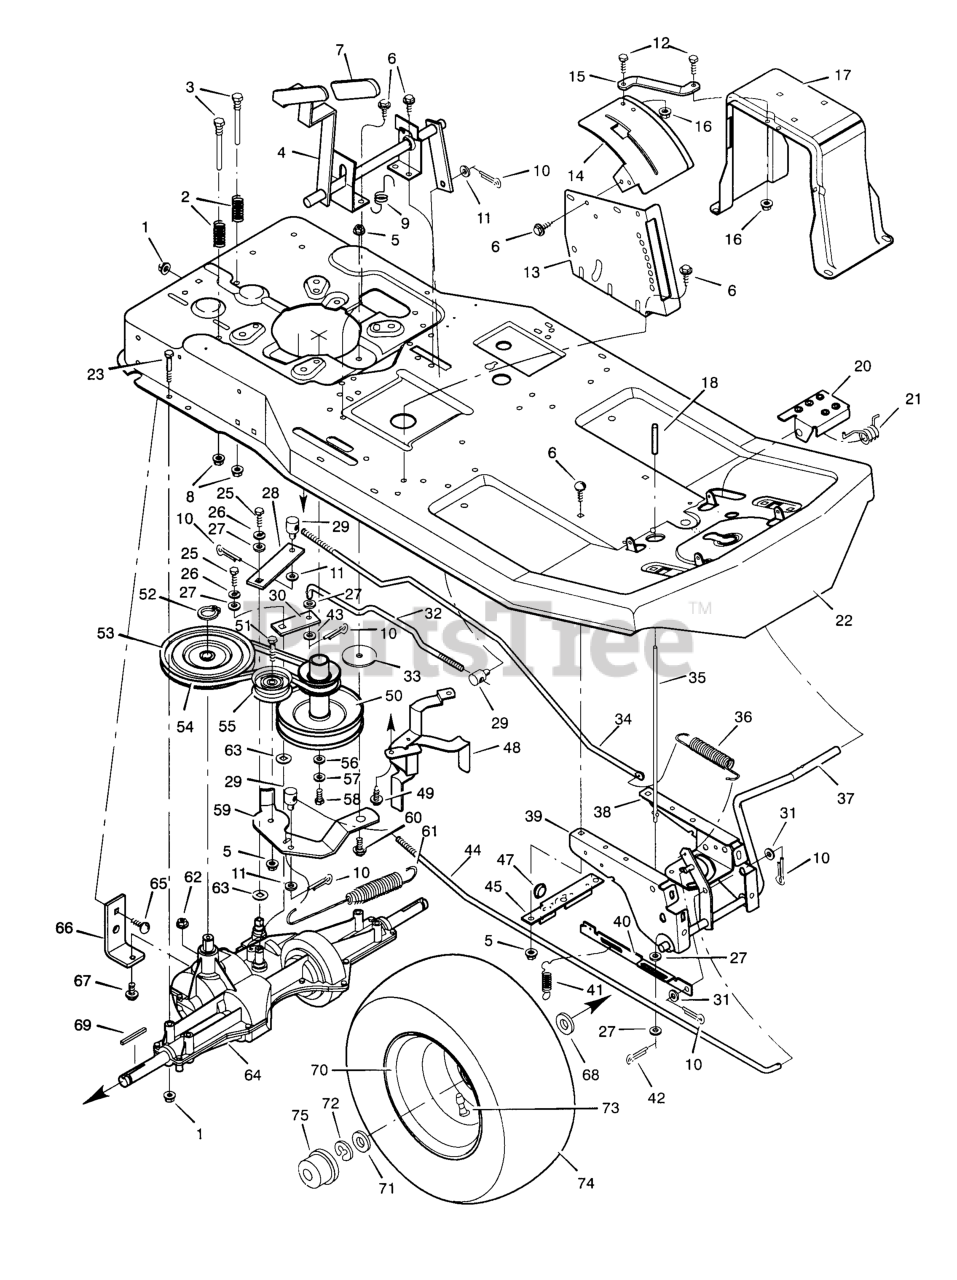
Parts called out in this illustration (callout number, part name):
1	Locknut, Flange
2	Spring, Compression
3	Guide, Belt
4	Shifter Assembly
5	Locknut, Flange
7	Grip, Shift Lever
8	Hex Nut
9	Spring, Extension
10	Pin, Cotter
11	Washer
12	Bolt, Hex
13	Plate, Index
14	Gate, Shift
15	Brace, Shift Gate
16	Locknut, Flange
17	Support, Seat
18	Grip, Parking Brake
20	Pedal
22	Frame Assembly
23	Bolt, Hex
25	Bolt, Hex
26	Lockwasher
27	Washer
28	Yoke, Brake
29	Nut, Adjusting
30	Yoke, Shift
31	Washer
32	Rod, Shift
33	Washer, Hardened
34	Rod, Brake
35	Rod, Parking Brake
36	Spring, Extension
37	Lever, Pedal
38	Plate, Left Suspension
39	Plate, Right Suspension
40	Link, Parking Brake
41	Spring, Extension
42	Pin, Cotter
43	Washer
44	Rod, Clutch
45	Stop, Parking Brake
47	Grommet
48	Guide, Belt
50	Pulley Assembly, Stack
51	Bolt, Hex
52	Ring, Retainer
53	Pulley, Drive
54	Belt, Motion Drive
55	Pulley, Idler
57	Lockwasher
58	Bolt, Hex
59	Bracket, Idler
60	Bolt, Shoulder
61	Spring, Extension
62	Locknut, Hex
64	Transaxle, Dana Model 4450-1 **
65	Bolt, Carriage
66	Bracket, Transaxle
67	Bolt, Hex
69	Key, Square
70	Wheel & Tire Assembly
73	Valve Stem
74	Tire *
75	Hub Cap
